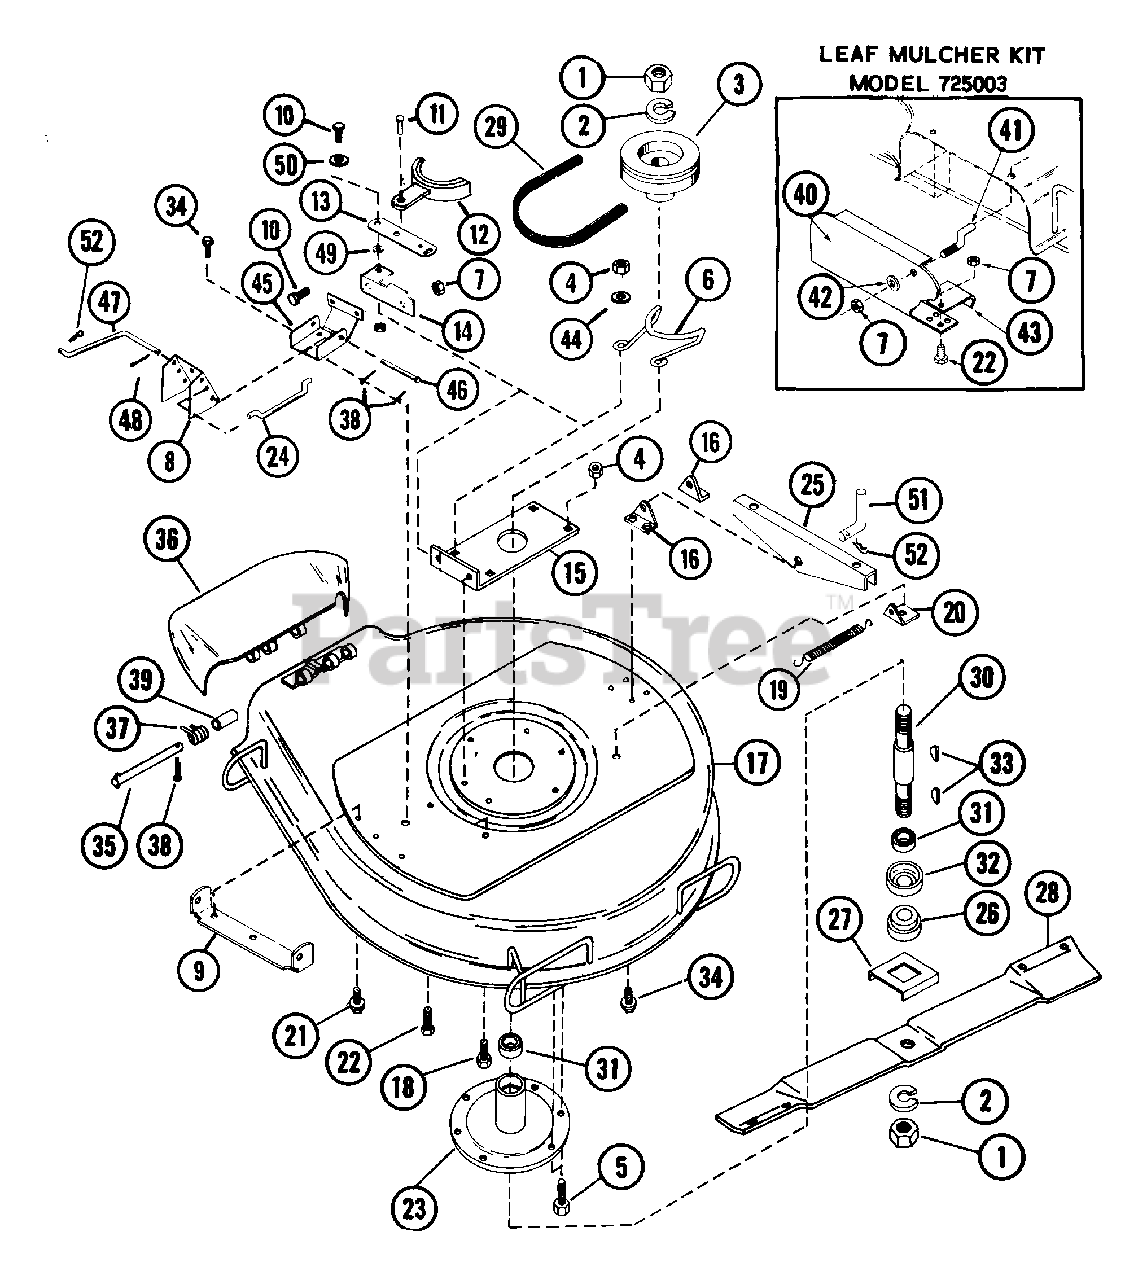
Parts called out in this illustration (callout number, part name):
1	NUT-JAM .75-10 PL
2	WSHR-LK .750X.188 MED PL
3	MOWER SHEAVE
4	NUT-LK-CTR .375-16 GR A PL
5	BLT-HEX .38-16X1.00 PL
6	MOWER BELT FINGER
7	NUT-LK .312-18 GR A PL
8	MOWER ENGAGING ARM
9	FRONT MOUNTING BRACKET
10	BLT-HEX .31-18X.63 PL GR 2
11	RVT .25X.50 RH ST
12	BLADE BRAKE
13	MOWER BRAKE LEVER
14	BRAKE BRACKET
16	REAR MOUNTING BRACKET
17	30 IN MOWER PAN W/ DECALS
18	BLT-SERHFWH .25-20X.50 PL
19	SG-TENS .072X.51X5.31 WLD 25
20	BRAKE CLIP
21	BLT-SCRHFWH .38-16X.50 PL
22	BLT-HEX .31-18X.50 PL GR2
23	SPINDLE HOUSING
24	MOWER BRAKE LINK
25	SWIVEL BRACKET
26	RETAINER HUB
27	BLADE TRAY
28	MOWER BLADE 30
29	V-BELT
30	SPINDLE SHAFT
31	BRG-BALL .750X1.781X.61
32	BEARING SLINGER
33	KEY-WDRF .188X.75X.313 SAE 9
34	BLT-SERHFWH .31-18X.50 PL
35	CLEVIS PIN
36	PAN CHUTE EXTENSION
37	SG-TORS .095X.50X 1.0
38	PIN-COTR .09X.75 PL
39	BSHG-SLV .334 X .502 X 1.437
40	LEAF MULCHER KIT-EMPEROR
42	WSHR-FL-STL .38X.875X.083 PL
43	MULCHER BRACKET
44	WSHR-FL-STL .406X.865X.094 PL
45	PIVOT BRACKET
46	PIN-CLEV .309X3.50 SP
47	MOWER ENGAGEMENT LINK
48	PIN-COTR .12X.75 PL
49	SPACER
50	WSHR-FL-STL .328X1.0X.094
51	CLEVIS PIN
52	PIN-HAIR INT .08X.38X1.42 YWZC
